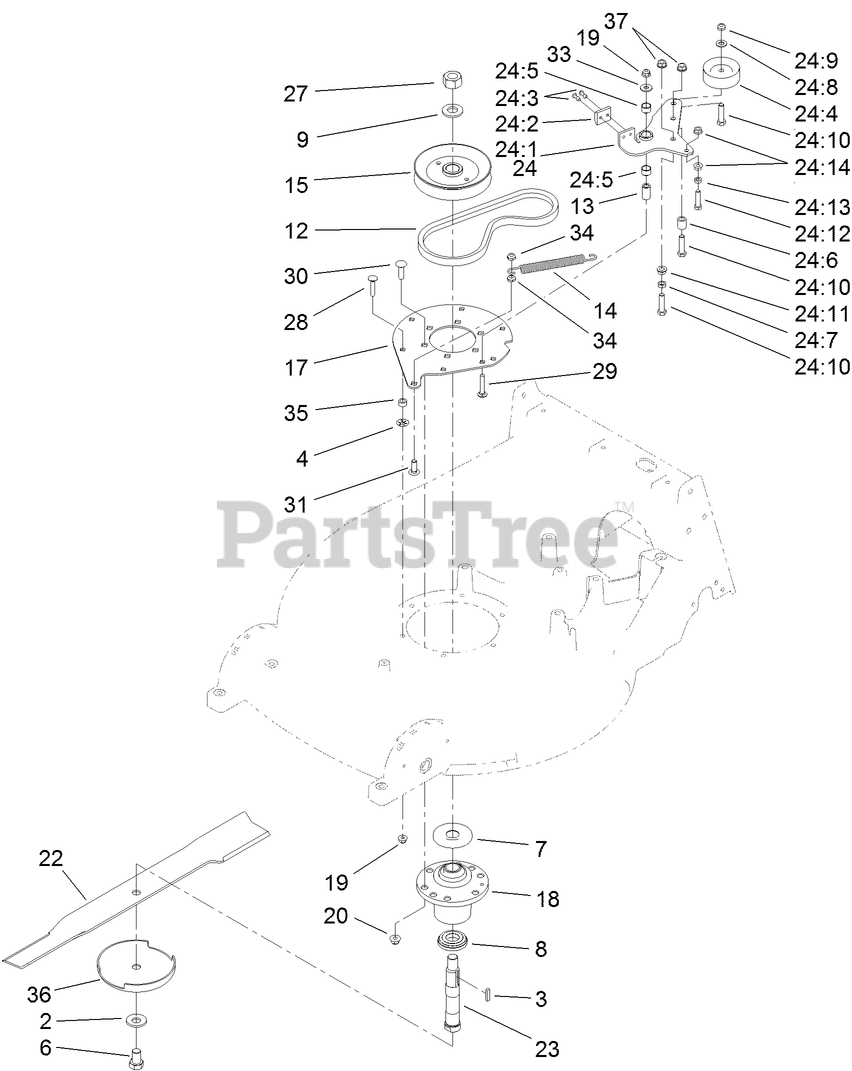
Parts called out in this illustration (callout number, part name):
2	WASHER-SPRING
3	KEY-RECTANGLE
4	RING-RETAINING
6	SCREW-CAP
7	Guard-Bearing, Top
8	SPACER-GUARD, BOTTOM
9	WASHER
13	BUSHING-ARM, IDLER
14	SPRING-BRAKE
15	SHEAVE-SPLIT, STEEL (W/HUB)
17	PLATE-ADAPTER, HOUSING
18	CUTTER HOUSING ASM
19	NUT-HF, NI
20	NUT-HF, NI
23	SHAFT-SPINDLE
24	IDLER ARM ASM
24:1	ARM-IDLER
24:2	PAD-BRAKE
24:3	RIVET-POP
24:4	PULLEY-IDLER
24:5	BEARING
24:6	BUSHING-LEVER, LIFT
24:7	NUT-JAM
24:8	WASHER-FLAT
24:9	NUT-LOCK, NI
24:10	SCREW-HH
24:11	NUT-HHF, WHIZ
24:12	SCREW-HH
24:13	NUT-JAM
24:14	NUT-HF
27	NUT-HH
28	BOLT-CARR
29	SCREW-CARR
30	SCREW-CARR
31	SCREW-CARR
33	WASHER-FLAT
34	NUT-LOCK, NI
35	SPACER
36	CUP-SCALP, ANTI
37	NUT-HHF, WHIZ
